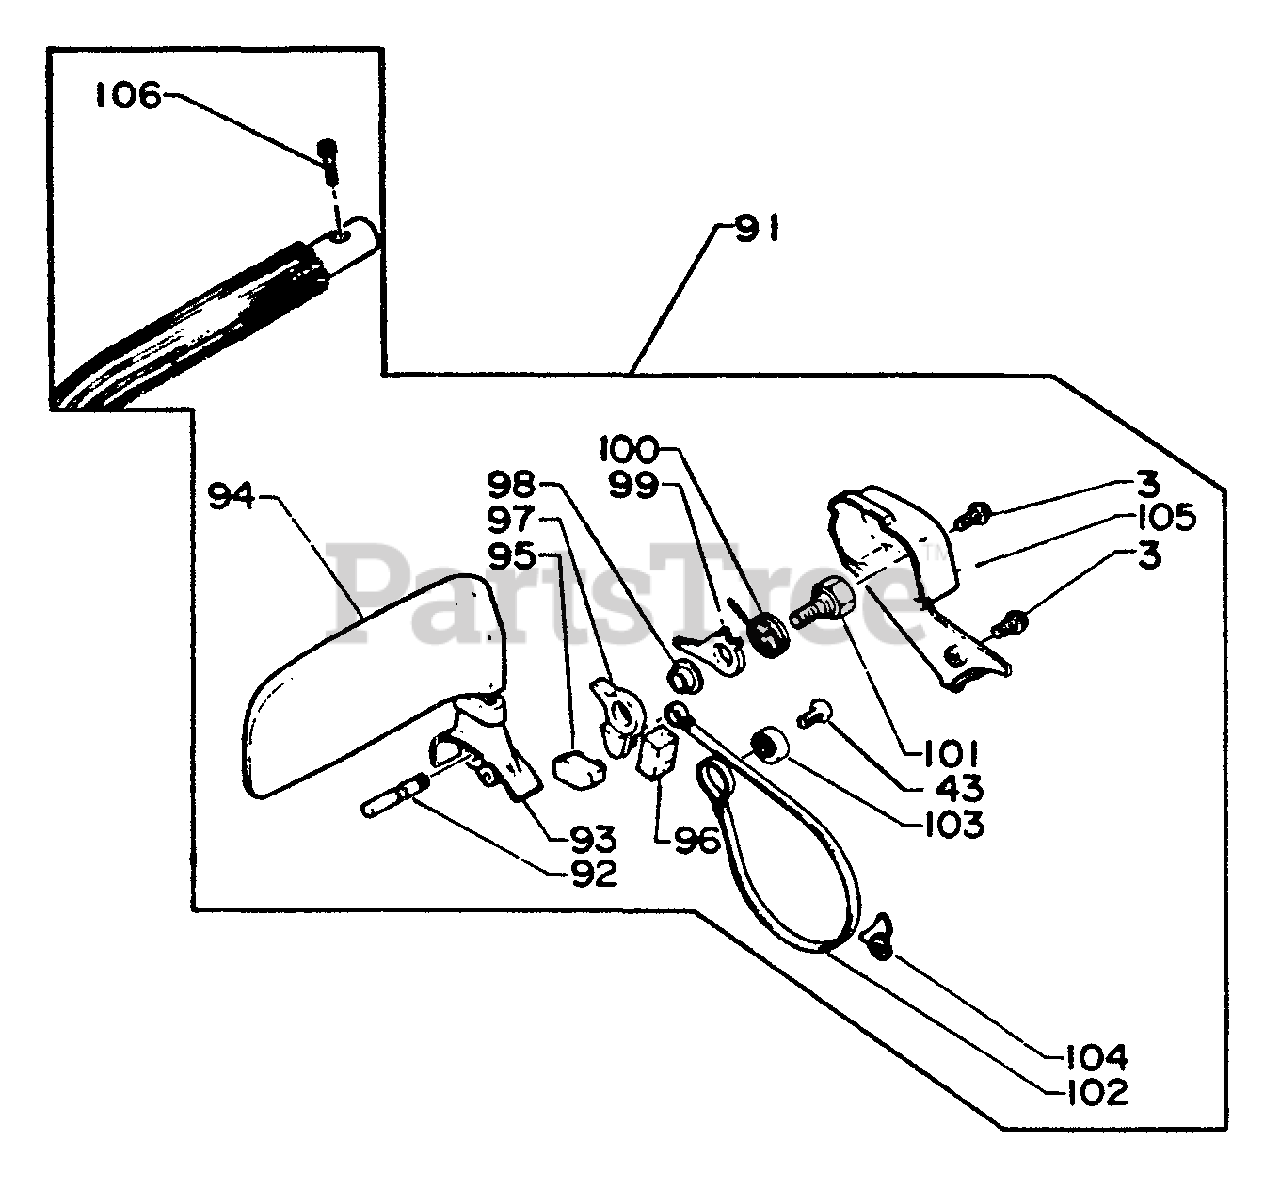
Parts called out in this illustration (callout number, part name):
3	SCREW - 4X12
43	SCREW - 5X10
91	CHAIN BRAKE ASSY
93	COVER, BRAKE
94	LEVER, BRAKE
95	RESET, BRAKE
96	SEAL
97	CONNECTOR
100	SPRING, RETURN
102	BAND, BRAKE
103	ADJUSTER, BRAKE BAND
104	RETAINER, BRAKE BAND
106	SCREW - 5X25
